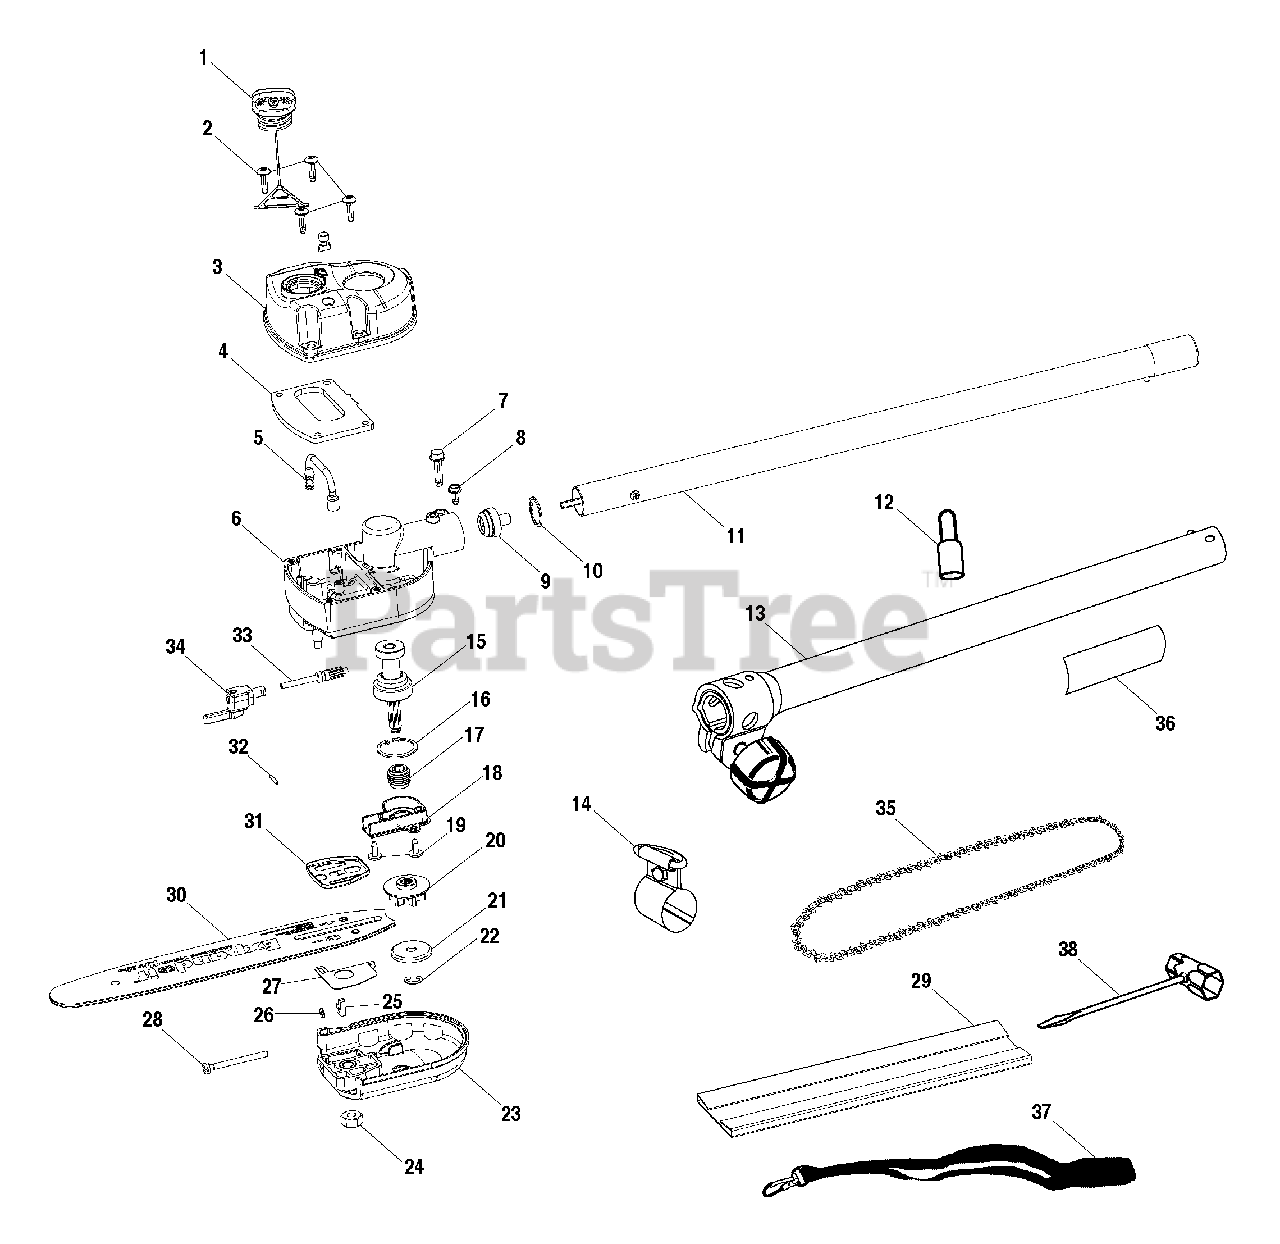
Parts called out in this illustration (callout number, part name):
1	OIL CAP
3	OIL TANK COVER ASSEMBLY
4	OIL COVER GASKET
5	PICK UP TUBE ASSEMBLY
6	GEAR HOUSING
7	SCREW (1/4-20 X 1 in.)
8	SCREW (10-24 X 1/2 in.)
9	PINION ASSEMBLY
10	RETAINING RING
11	LOWER DRIVE SHAFT ASSEMBLY
12	HANGER CAP
13	INTERMEDIATE DRIVESHAFT ASSEMBLY
14	STRAP HANGER
15	GEAR ASSEMBLY
16	RETAINING RING
17	WORM GEAR
18	OIL PUMP HOUSING
19	TRUSS HEAD SCREW
20	SPROCKET
21	CUPPED WASHER
23	BAR CLAMP ASSEMBLY
24	HEX NUT (5/16-18)
25	GUIDE BAR ADJUSTMENT PIN
26	RETAINING RING
27	GUIDE BAR PLATE
28	GUIDE BAR ADJUSTMENT SCREW
29	SCABBARD
30	GUIDE BAR
31	BAR PAD PLATE
32	OIL PUMP CAM PIN
33	GEAR AND PLUNGER
34	OIL PUMP SEAL
35	CHAIN
36	WARNING LABEL
37	HARNESS
38	COMBINATION WRENCH
39	8 oz. BOTTLE OF OIL
